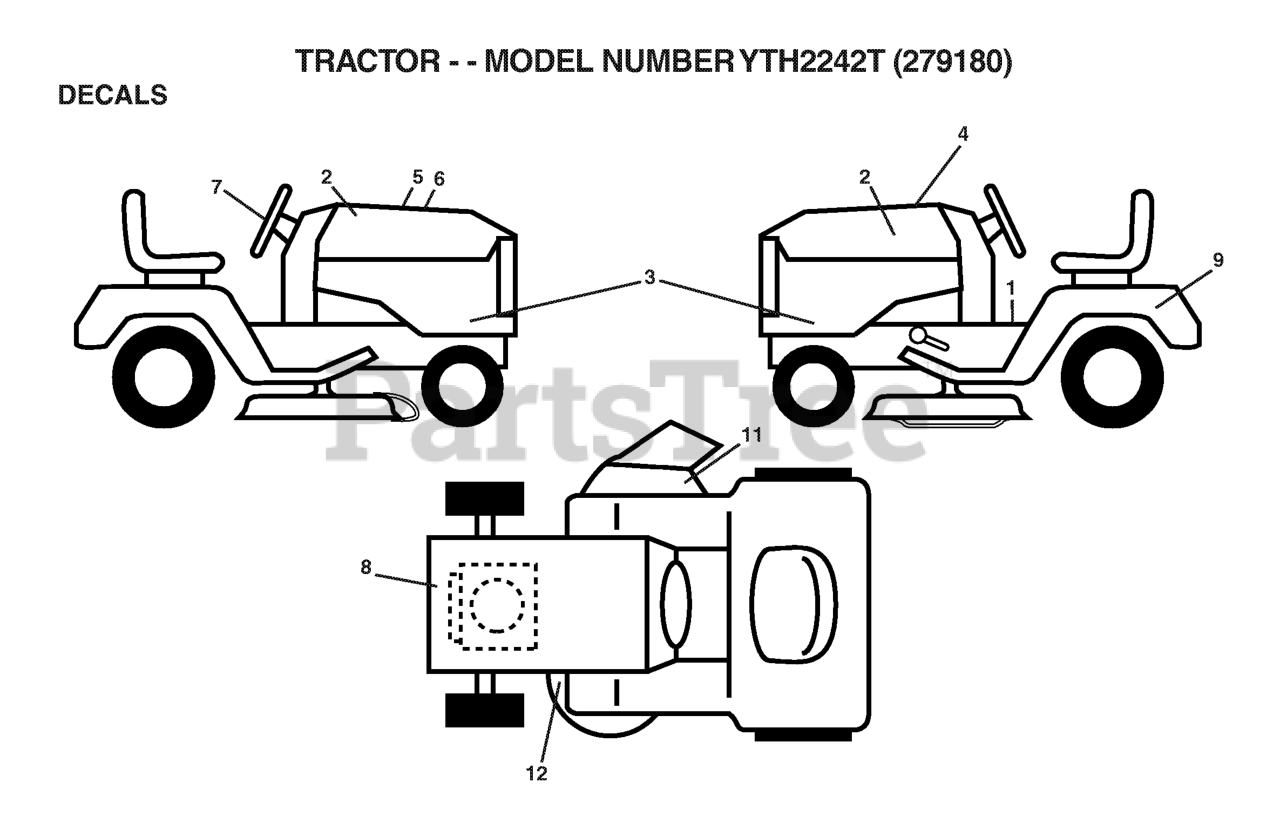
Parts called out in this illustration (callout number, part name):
2	DECAL.HOOD.NAMELOGO.HUSQ
4	DECAL.HOOD.TOP.INSERT.
5	DECAL HOOD CUST. RESP.
7	DECAL.STEERING.HUSQ.BLUE
8	DECAL.B&S.22HP#275796
9	DECAL BTRY SYMBOLS
11	DECAL.WARN.KEEP.HAND.AWAY
12	DECAL V BELT SCHEMATIC
